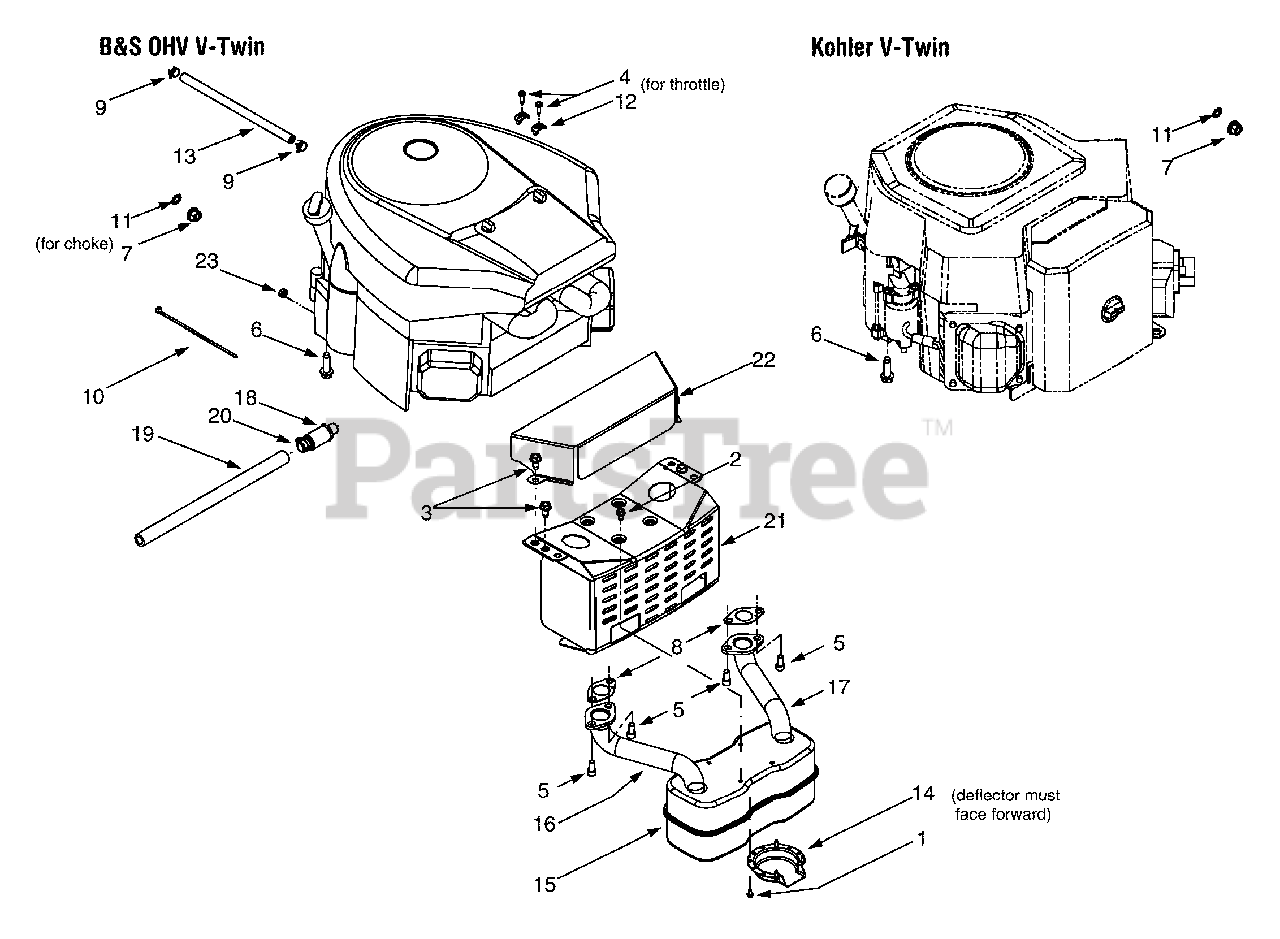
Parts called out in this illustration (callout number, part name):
1	Self-tapping Screw, #8-18 x.50
2	Self-tapping Screw, 1/4-20 x.50
3	Self-tapping Screw, 5/16-18 x.625
4	Screw, #10-32 x.625
5	Screw, 5/16-18 x.625
6	Self-tapping Screw, 3/8-16 x 1.25
7	Flange Lock Nut, 3/8-16
8	Exhaust Gasket
9	Hose Clamp
10	Cable Tie
11	Lock Washer,.406 x.875 x.059
12	Casing Clamp
13	Fuel Line Hose
14	Muffler Deflector
15	Muffler, Twin Inlet
16	RH Exhaust Pipe
17	LH Exhaust Pipe
18	Oil Drain Valve
19	Oil Drain Hose
20	Oil Drain Cap
22	Engine Heat Shield
23	Hex Nut, 1/4-20
